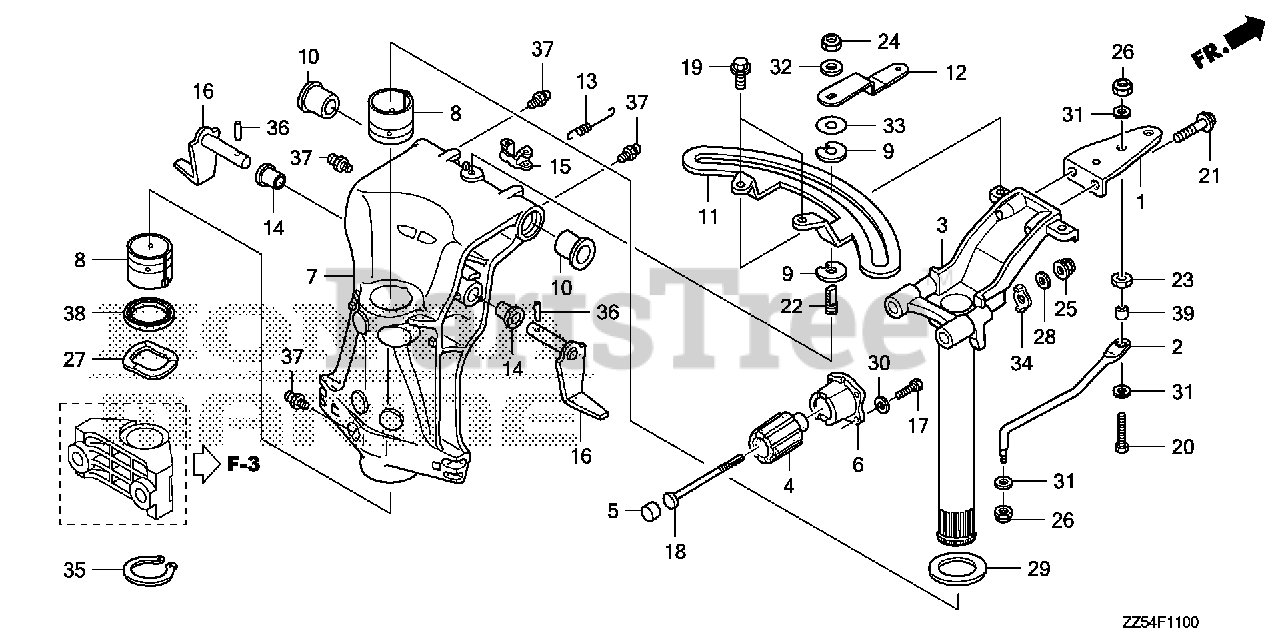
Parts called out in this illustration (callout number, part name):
1	PLATE, STEERING
2	ROD, STEERING
3	FRAME, MOUNTING
4	RUBBER, MOUNTING (UPPER)
5	RUBBER, MOUNTING (UPPER) (B)
6	HOLDER, MOUNTING (UPPER)
7	CASE, SWIVEL *NH282MU* (OYSTER SILVER METALLIC-U)
8	LINER, SWIVEL CASE
10	BUSH, SWIVEL CASE
13	SPRING, TILT LEVER
14	BUSH, TILT ARM
15	BRACKET, TILTING
16	STOPPER, TILT
17	BOLT, HEX. (6X18)
18	BOLT, SPECIAL (10X130)
20	BOLT (3/8-24UNF)
21	BOLT, FLANGE (10X25)
23	NUT (3/8-24UNF)
25	NUT, FLANGE (10MM)
26	NUT, SELF-LOCK (3/8-24UNF)
27	WASHER, WAVE (40MM)
28	WASHER, PLAIN (10MM)
29	WASHER, THRUST (34MM)
30	WASHER, PLAIN (6MM)
31	WASHER (10MM)
34	WASHER, SPECIAL
35	CIRCLIP (OUTER) (39MM)
36	PIN, SPRING (2.5X20)
37	NIPPLE, GREASE
38	OIL SEAL (39.5X52X6) (ARAI)
39	COLLAR, STEERING ROD
